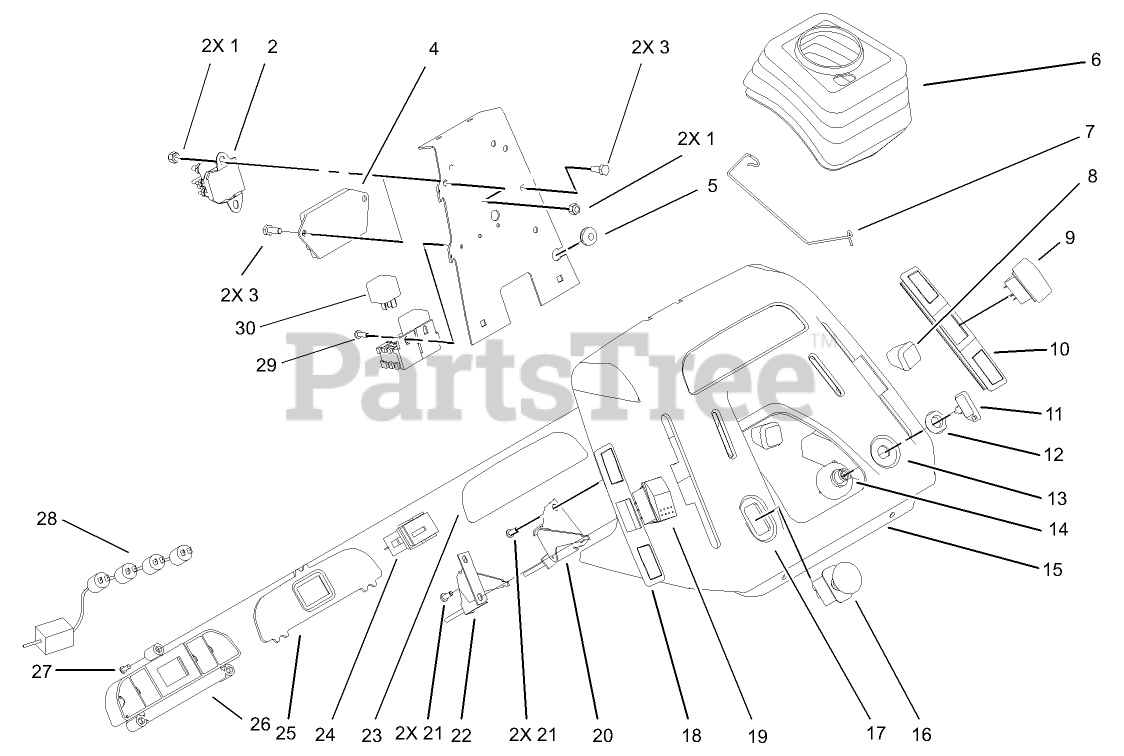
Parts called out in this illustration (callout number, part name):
1	NUT-LOCK, NI
2	SOLENOID-STARTER
3	SCREW-HH
4	MODULE-NMIR, LOW BATTERY
5	GROMMET-RUBBER
6	BOOT-STEERING
7	CLIP-BOOT
9	SWITCH-CRUISE
10	COVER-SLOT, RH
11	KEY-IGNITION
13	DECAL-THROTTLE, IGNITION
14	SWITCH-IGNITION
16	SWITCH-PTO,ON-ON-NONE
17	DECAL-PTO / CHOKE
18	COVER-LIFT
19	SWITCH
20	CONTROL-THROTTLE (TWIN)
22	CHOKE CONTROL ASM
23	DECAL-DASH, LENS
24	HOURMETER
25	LENS-DASH
26	HOUSING-LIGHT
27	SCREW
28	HARNESS-LIGHT, SIX
29	SCREW-PPHTF
30	RELAY
